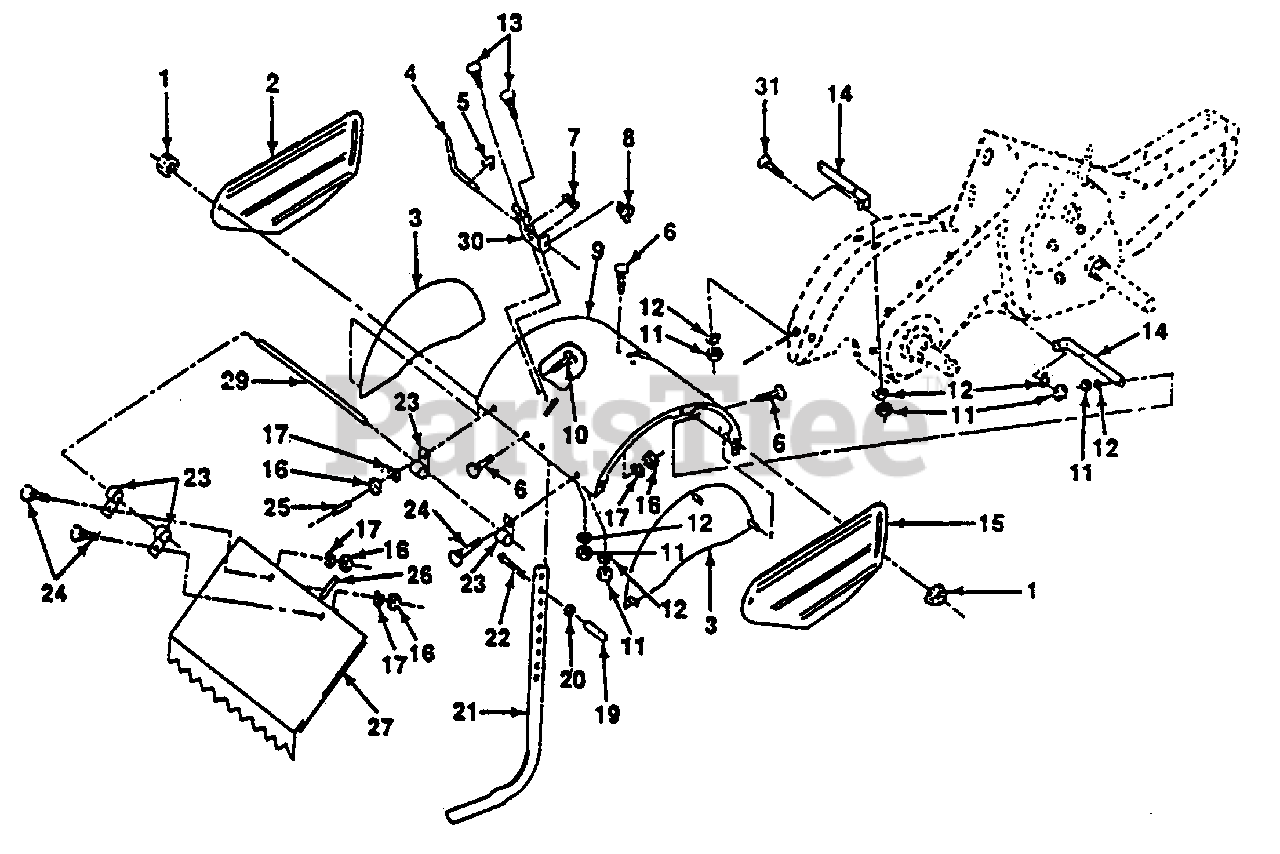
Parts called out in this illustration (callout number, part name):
1	Nut, Flange 5/16-18 (AYP part number)
2	Shield, Side, Outer L.H. (AYP part number)
3	Shield Side (AYP part number)
4	Pin, Stake, Depth (AYP part number)
5	Ring, Klip (AYP part number)
6	Bolt, Carriage 5/16-18 x 3/4 Gr 5
7	Spring (AYP part number)
8	Spring, Stake, Depth (AYP part number)
9	Shield, Tine (AYP part number)
10	Bolt, Carriage 1/4-20 x 1-1/4 Gr. 5 (AYP part number)
11	Nut, Hex 5/16-18 (AYP part number)
12	Washer, Lock 5/16 (AYP part number)
13	Bolt, Carriage 5/16-18 x 1 (AYP part number)
14	Bracket, Shield, Tine (AYP part number)
15	Shield, Side, Outer R.H. (AYP part number)
16	Nut, Hex 1/4-20 (AYP part number)
17	Washer, Lock 1/4 (AYP part number)
19	Grip (AYP part number)
20	Nut, Hex 3/8-16 (AYP part number)
21	Stake, Depth (AYP part number)
22	Bolt, Hex 3/8-16 x 2 (AYP part number)
23	Hinge (AYP part number)
24	Bolt, Carriage 1/4-20 x 1/2 Gr. 5 (AYP part number)
25	Cap, Vinyl (AYP part number)
26	Pad, Idler (AYP part number)
27	Shield, Leveling (AYP part number)
29	Pin, Hinge (AYP part number)
30	Bracket, Latch (AYP part number)
31	Bolt, Carriage 5/16-18 x 1-1/4 (AYP part number)
